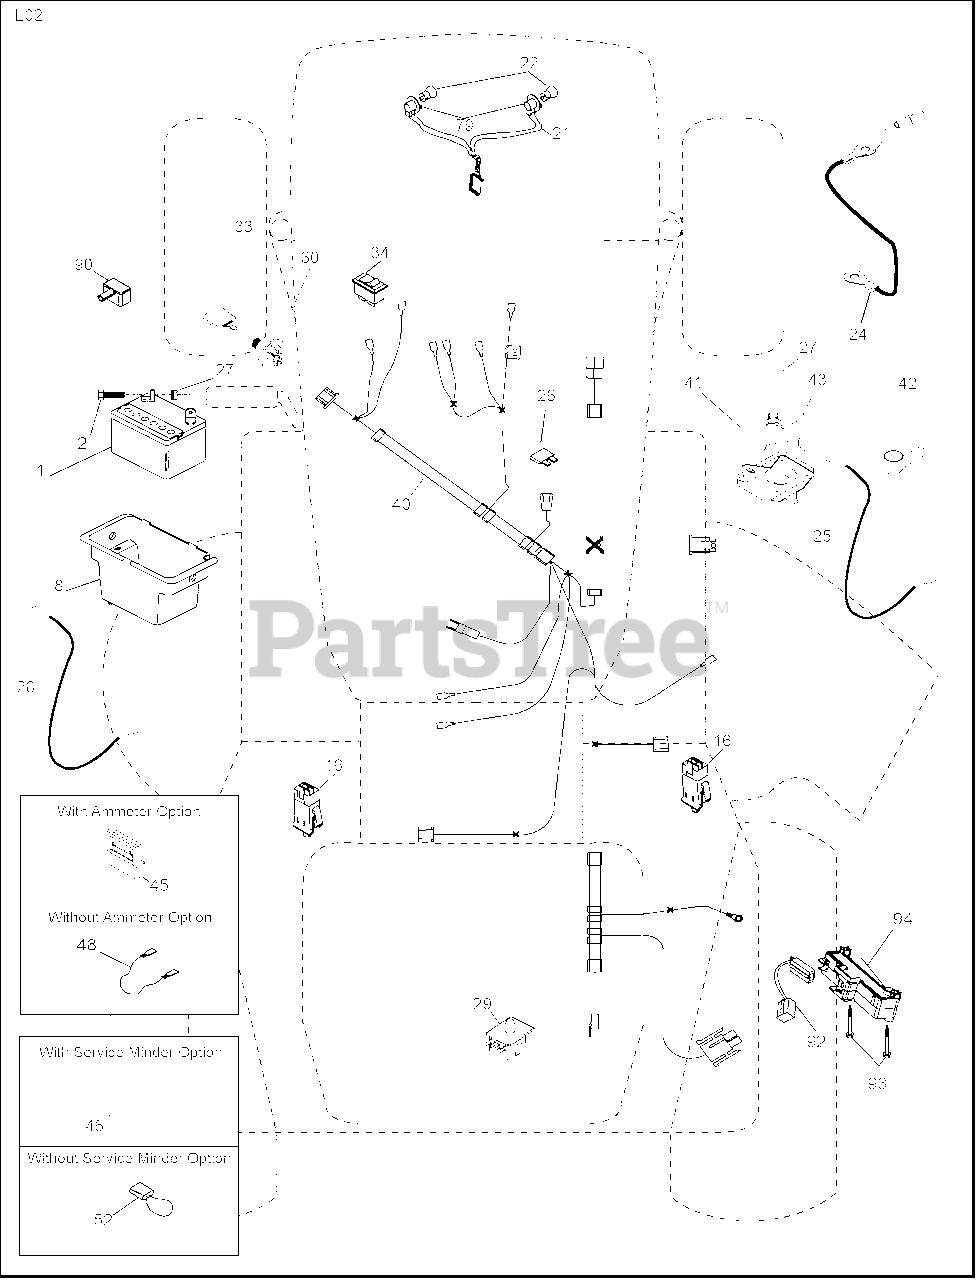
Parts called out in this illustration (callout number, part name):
1	Battery
2	Bolt Hex Hd 1/4-20 unc x 3/4
8	Box Battery
16	Switch Interlock
21	Harness Asm Light w/4152j
22	Bulb Light #1156
24	Cable Battery 6 Ga. 11"red
25	Cable Battery
26	Fuse 20 AMP
27	Nut Keps Hex 1/4-20 unc
28	Cable Ground 6 Ga. 12" Black
29	Switch Seat
30	Switch Ign
33	Key/Chain
34	Switch Light/Reset
40	Harness Ign
41	Bolt Blk Fin Hex 1/4-20
42	Cover Terminal Red
43	Solenoid
48	Adapter Ammeter
52	Protection Wire Loop
79	Socket Asm Bulb
90	Cover Terminal Battery
92	Harness Pigtail
93	Screw Plastite 10-14 x 2.0
94	Module Reverse ROS
